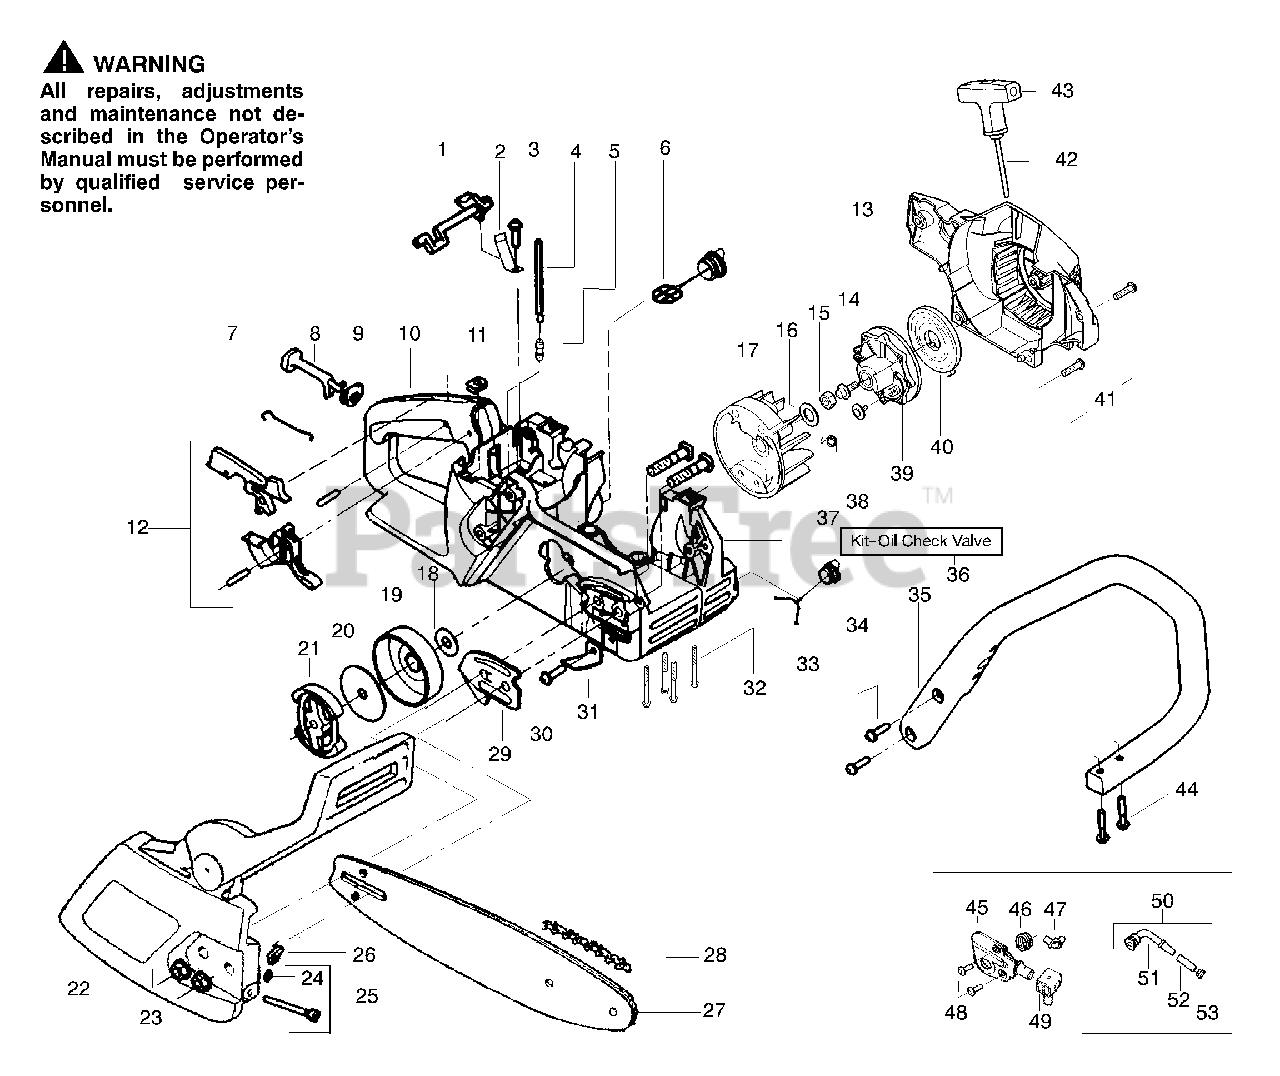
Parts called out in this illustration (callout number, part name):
1	Lever-Switch
2	Spring-Switch
4	Kit-Fuel Line (Large)
6	Assy-Fuel Cap
7	Wire-Throttle
8	Lever-Choke
9	Grommet-Choke Knob
10	Assy-Chassis
11	Nut-Speed
12	Kit-Trigger & Lockout
13	Housing-Fan
15	Nut-Flywheel
16	Washer-Flywheel
17	Assy-Flywheel
18	Washer - Thrust
19	Assy-Drum W/brg.
20	Washer-Clutch
21	Assy. - Clutch
22	Assy-Chain Brake
23	Nut-Bar Mounting
24	Retainer-Bar Adjust
25	Kit-Bar Adjust
26	Pin-Bar Adjust
27	Bar 16"
28	Chain 16"
29	Plate-Bar Mounting
31	Chain Catcher
33	Assy-Oil Cap
35	Handle-Front
36	Kit-Oil Check Valve
37	Spring - Starter Dog
39	Pulley-Starter
40	Spring-Starter
42	Kit-Rope
43	Handle-Starter
45	Kit-Oil Pump
46	Gear-Worm Spring
47	Elbow-Oil Pickup
49	Seal Block
50	Assy-Oil-Pickup
51	Pickup-Oiler
52	Filter-Oil
53	Plug-Oil Filter
